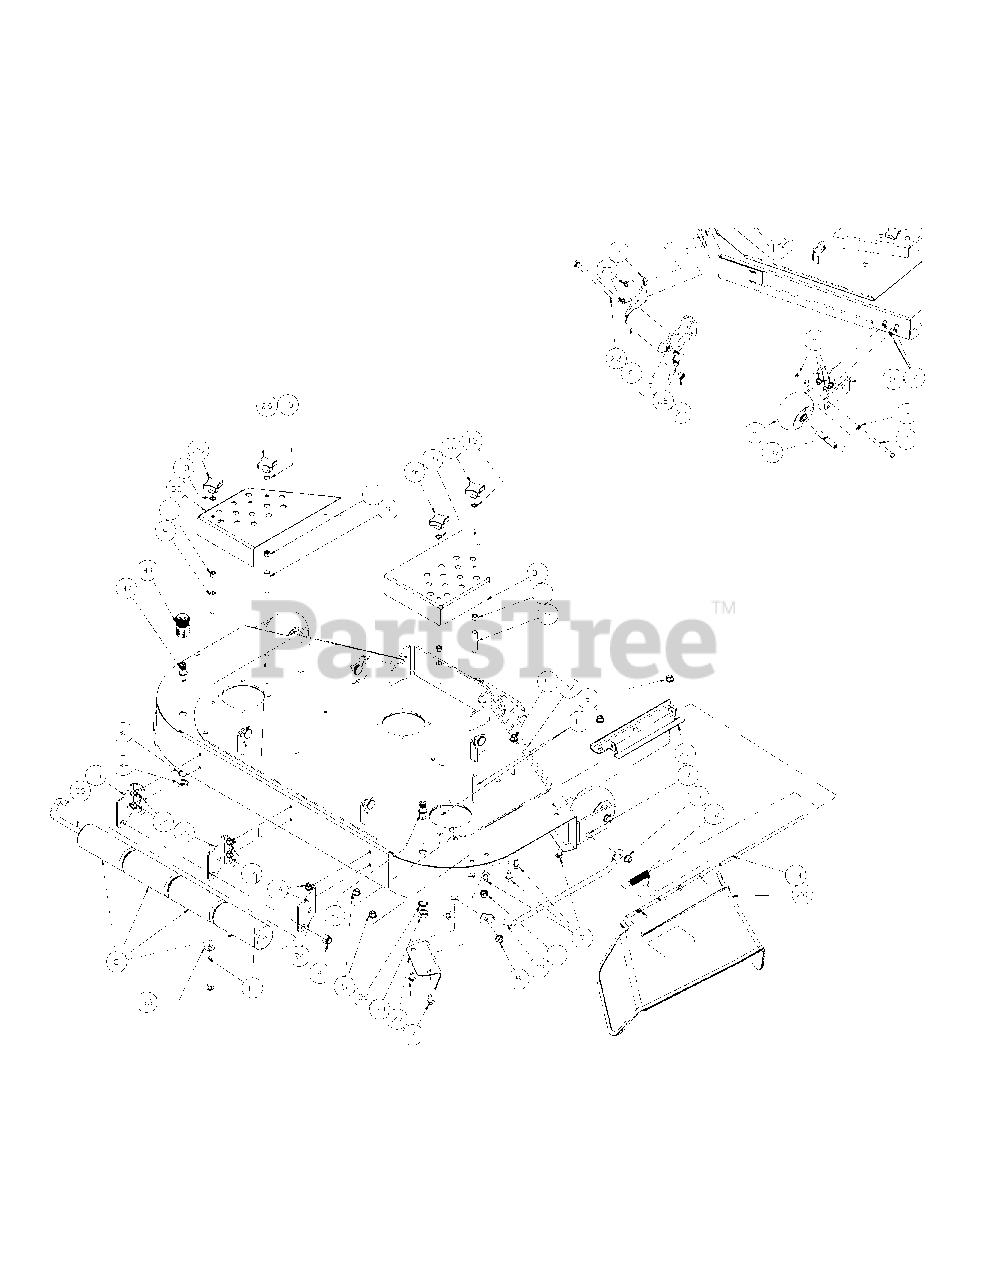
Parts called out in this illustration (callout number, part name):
1	Hex Nut 3/8-16
2	Hex Cap Screw, 3/8-16, 3.75
4	Hex Nut, 1/2-13, Insert Lock
5	Hex Nut, 3/8-16 Flange Lock
6	Complete Wheel, 5.00 Dia
7	Carriage Bolt 3/8-16 x .75
8	Front Roller
9	Spacer Stop Deck
10	Wheel Spacer
11	Carriage Bolt, 3/8-16 x 3.5 Lg
12	Torsion Spring
13	Chute Deflector Rod
14	Self Tapping Screw, 5/16-18 x 1/2
19	External Washer, 3/8
20	Deflector Chute
21	Deflector Chute Bracket
22	Hex Cap Screw, 1/2-20 x 7.50
23	Fabricated Deck Finger Guard
25	Self Tapping Screw, 3/8-16 x 0.875
26	Plastic Knob
27	Fabricated Deck, Chute Bracket
28	Lock Nut, Nylon Insert, 1/2-20
29	J-Hook w/ Threaded Roller
32	44 Fabricated Deck Assembly
33	Hex Nut, M16-1.5
34	Water Nozzle Adaptor
35	Washer, .510 x 1.00 x .060
36	Lock Washer, 17 x 23.8 x 1.95
37	Deck Water Nozzle
